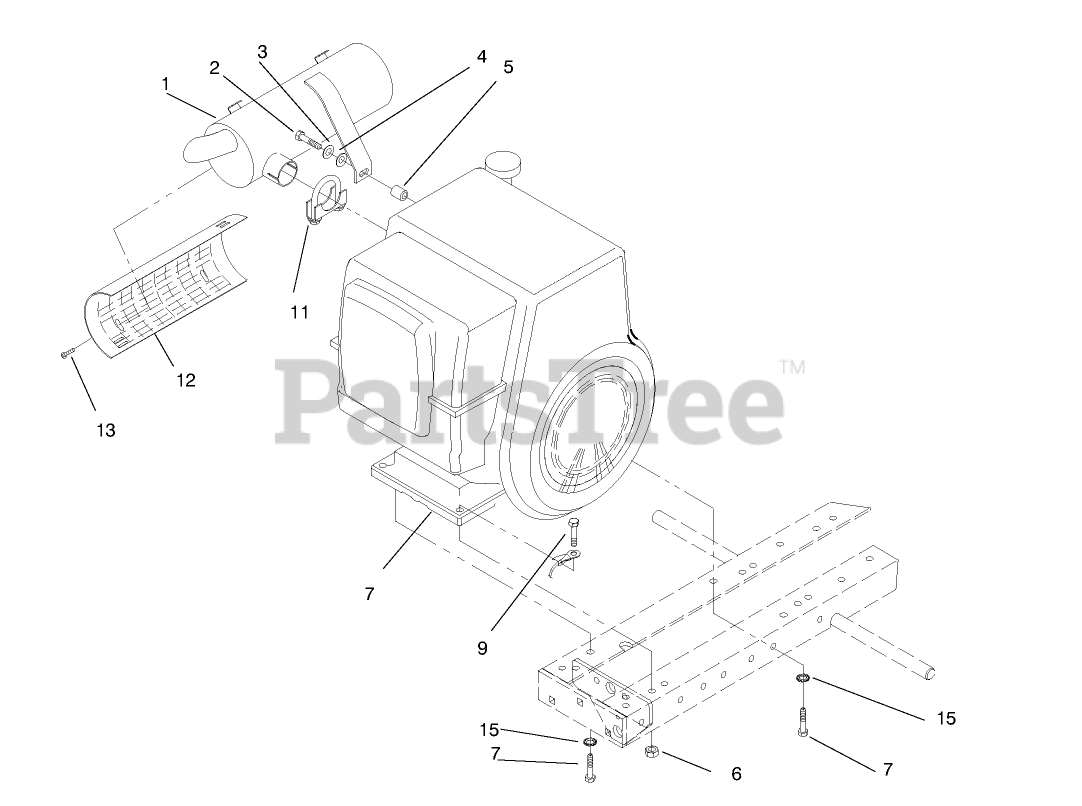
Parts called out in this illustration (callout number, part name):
1	MUFFLER
2	SCREW-HH
3	WASHER-LOCK
4	WASHER-PLAIN
5	SPACER
6	NUT-LOCK, NI
7	SCREW-HH
9	SCREW-HH
12	SHIELD-HEAT
13	SCREW
14	WIRE GROUND
15	WASHER-LOCK
